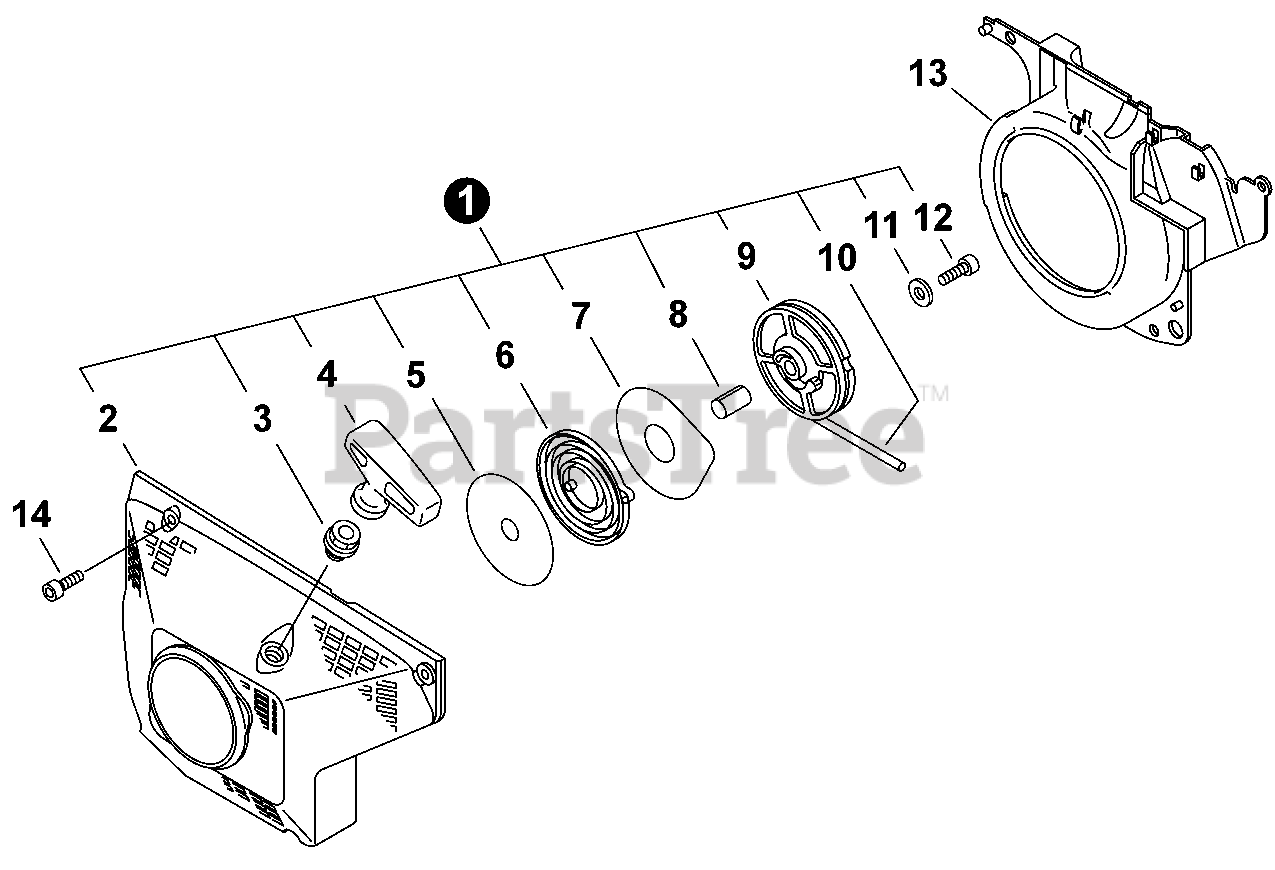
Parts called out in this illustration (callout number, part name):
1	STARTER ASSY
2	CASE, RECOIL STARTER
3	GUIDE, ROPE
4	GRIP, STARTER
5	PLATE, STARTER
6	SPRING, RECOIL
7	PLATE, STARTER
9	REEL, ROPE
10	ROPE, STARTER 4.0×950
11	WASHER 5.2×16×1.0
12	BOLT 5×14
13	COVER, FAN
14	BOLT 5×20
